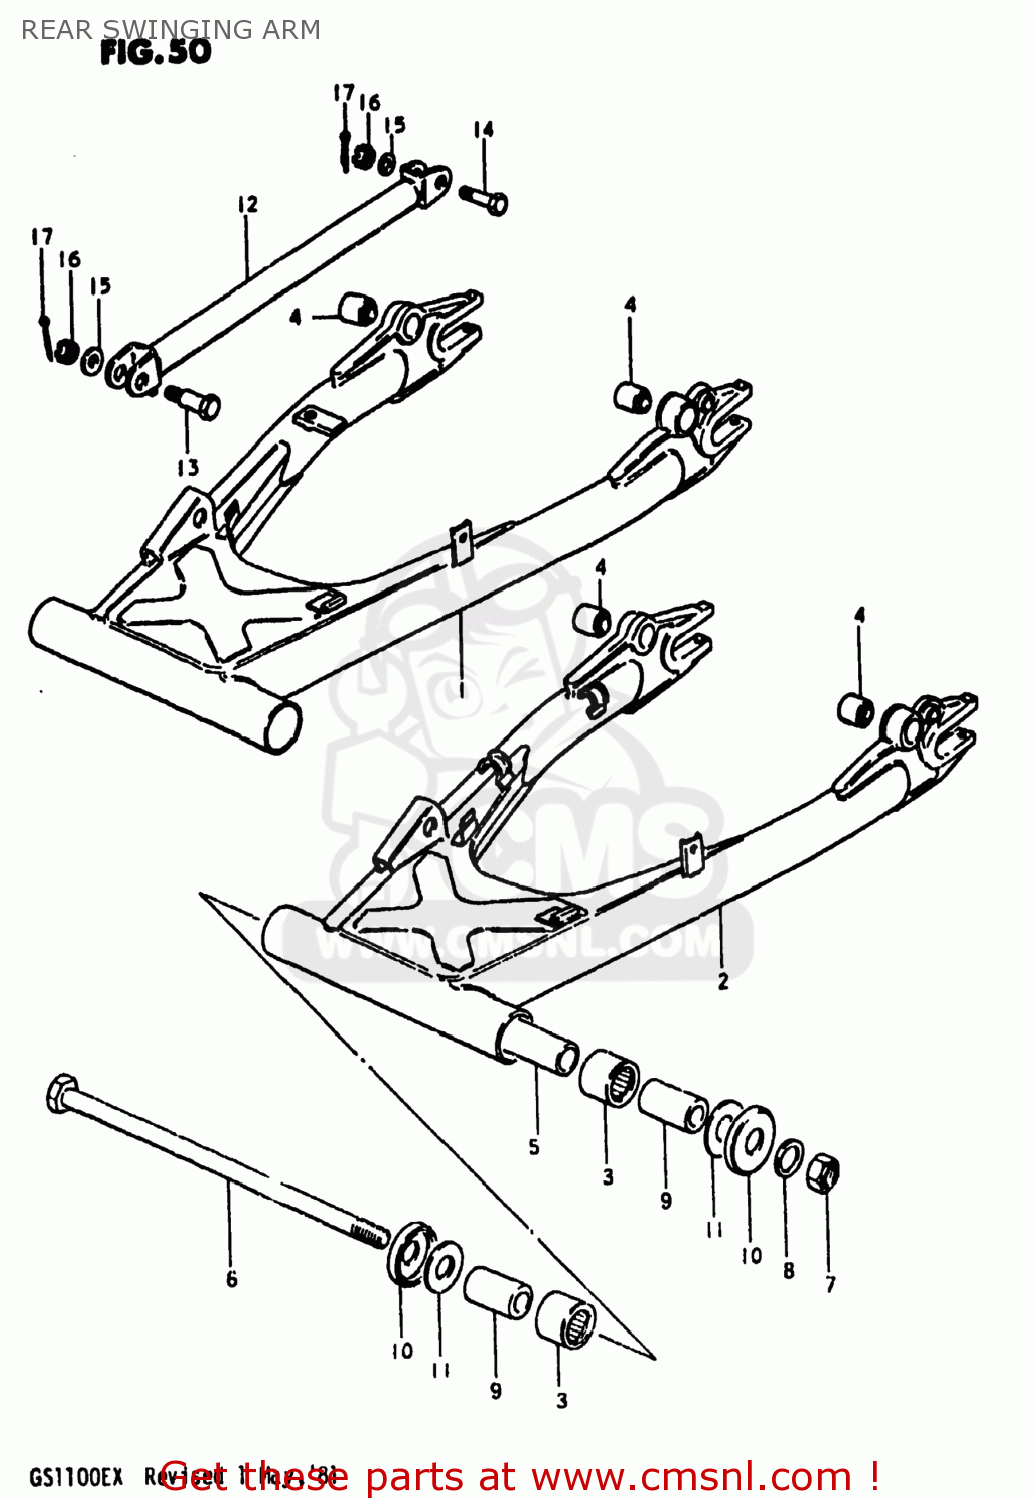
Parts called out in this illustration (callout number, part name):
1	REAR SWINGING ARM SET
2	REAR SWINGING ARM SET
3	BEARING(25X33X30)
4	BUSH
5	SPACER,RR SWGARM PIVOT CTR
6	SHAFT,REAR SWING ARM
7	NUT 16MM
8	WASHER
9	SPACER,RR SWGARM PIVOT
10	COVER, DUST SEAL
11	WASHER
12	TORQUE LINK, REAR
13	BOLT
14	BOLT(10X39)
15	WASHER
16	NUT
17	PIN 20X20
